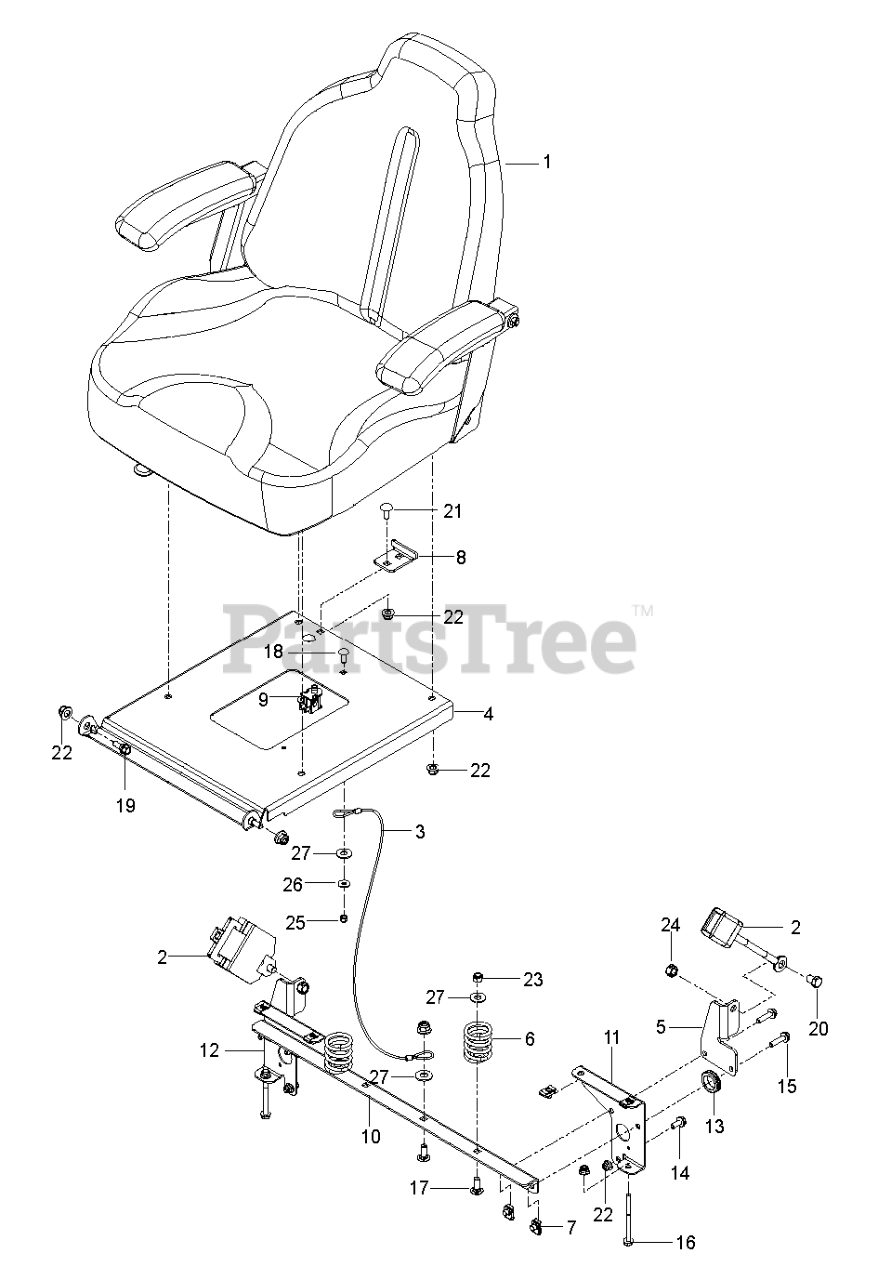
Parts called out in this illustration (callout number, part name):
1	SEAT.ASM.907.TRACK.W/O.BELT
2	SEAT BELT, RETRACTABLE
3	SEAT LANYARD
4	SUPPORT.SEAT.ORANGE
5	MOUNT.SEAT.BELT.BLACK
6	SPRING.COMPRESSION.SEAT.BLACK
7	U-CLIP 5/16-18 NUT RETAINER
8	STOP, SEAT - BLACK
9	SEAT SWITCH
10	SUPPORT.SEAT. BLK
11	SUPPORT.RT.BLK
12	SUPPORT.LT.BLK
13	RUBBER GROMMET
16	BOLT.HEX.FLNG.5/16-18X3.75
18	BOLT CUP HEAD SQUARE NECK BOLT
19	SB 5/16-18 HEX HD GD5, BLK ZN
20	HCS 7/16-20 X .75 GD 5
21	RHSNB 5/16-18 X 3/4 GR5 BLK ZN
22	NUT HEXAGON FLANGE 5/16-18 ST
24	NUT HEX 7/16F LOCK RP
25	NUT HEXAGON 1/4-20 ST ZPB
27	GSPW Washers
